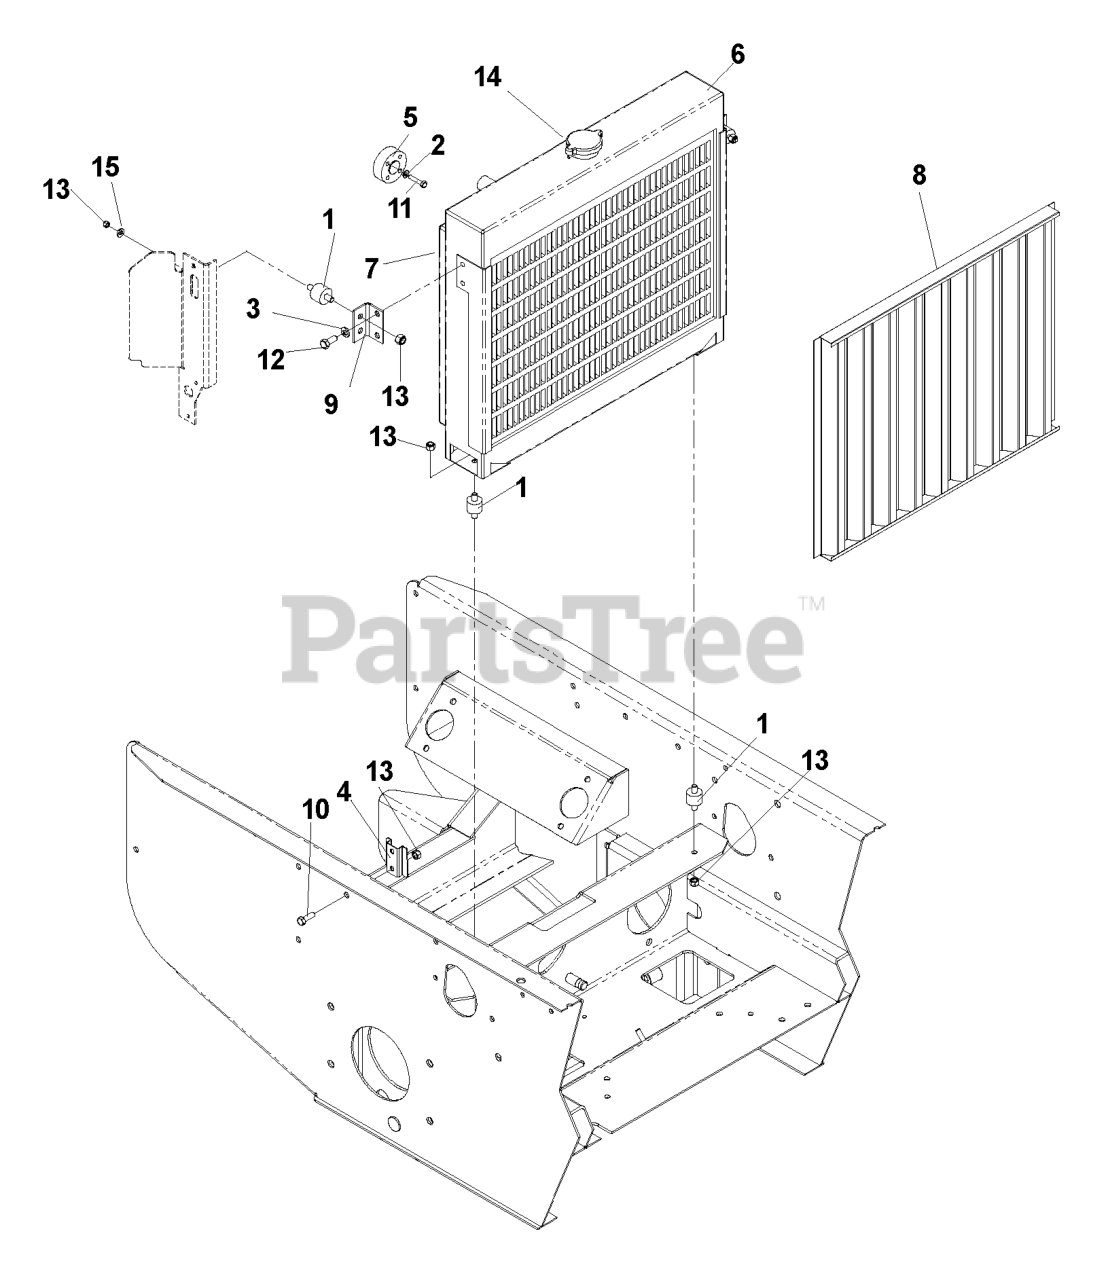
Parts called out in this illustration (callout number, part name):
2	LOCKWASHER 1/4"
3	WASHER.LOCK.HVY.HLCL.SPR.5/16
4	MOUNTING BRACKET
5	SPACER FAN
8	DEBRIS GUARD
9	BRACKET ISO
10	HCS 5/16C X 1
12	HCS 5/16C X 3/4
13	NUT 5/16 NYLOC
14	RADIATOR CAP
15	FLAT WASHER 5/16 SAE
